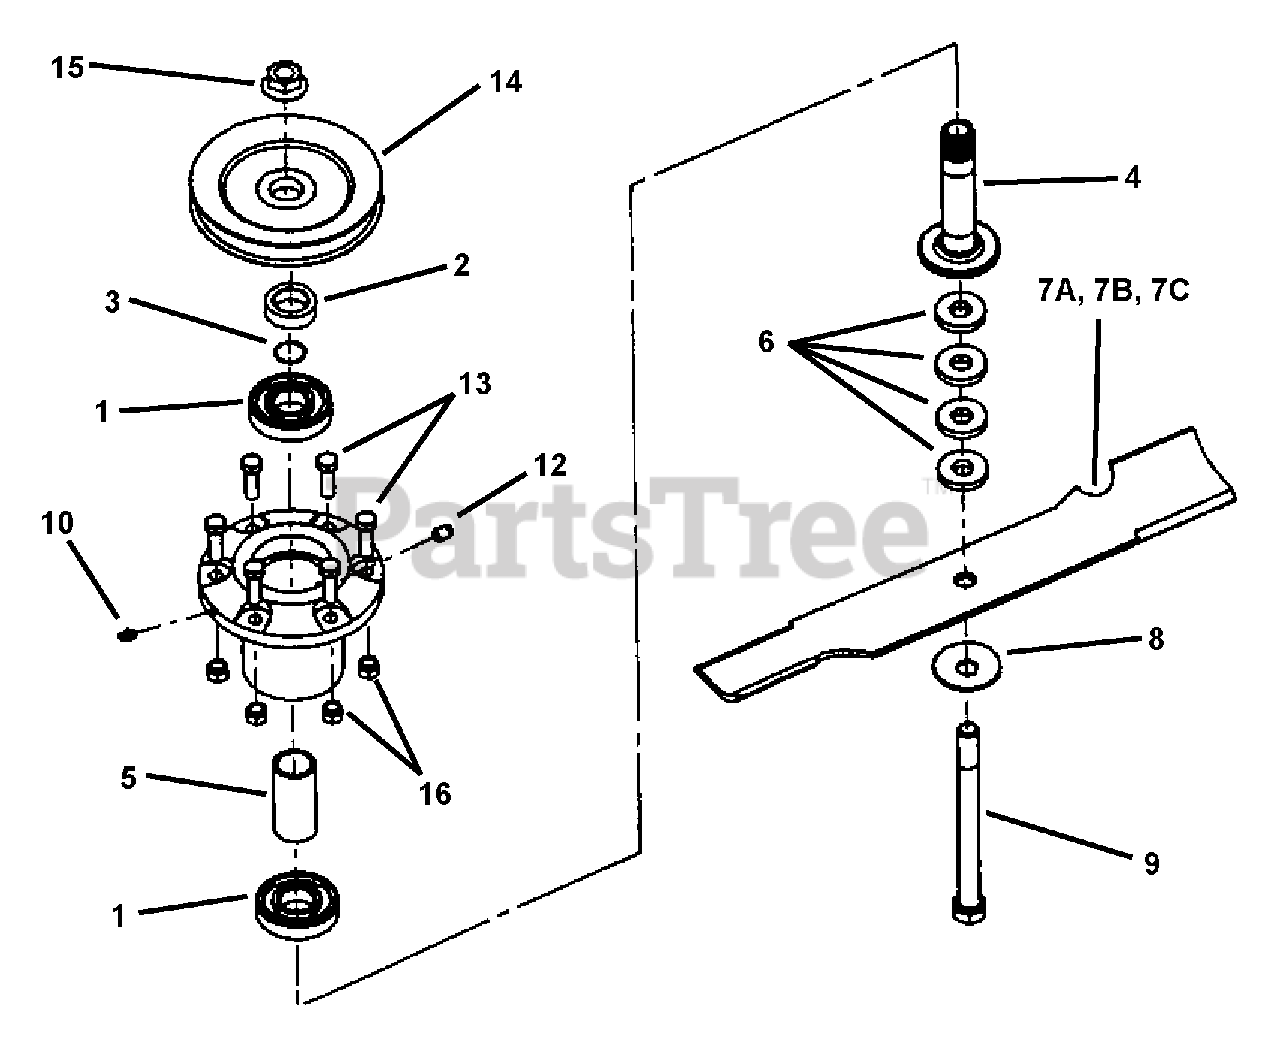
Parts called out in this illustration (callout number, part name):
1	BEARING, Sealed
2	WASHER, Spindle
3	SNAP-RING, Spindle Shaft
4	SHAFT, Spindle
5	SPACER, Bearing
6	SPACER, Blade
7A	BLADE, 18"
7B	BLADE, 21"
7C	BLADE, 16-5/16"
8	WASHER, Beveled
9	BOLT, 5/8-18 x 7-1/2" Hex Head Cap Grade 5
10	LUBE FITTING, 1/4-28 Thread Forming
12	VENT, Spindle
13	BOLT, 3/8-16 x 1-1/4" Rib Necked
14	PULLEY, 5-3/4" O.D.
15	NUT, 5/8-18 Hex Flange Lock, Grade 5
16	NUT, 3/8-16 HEX NYLON LOCK
